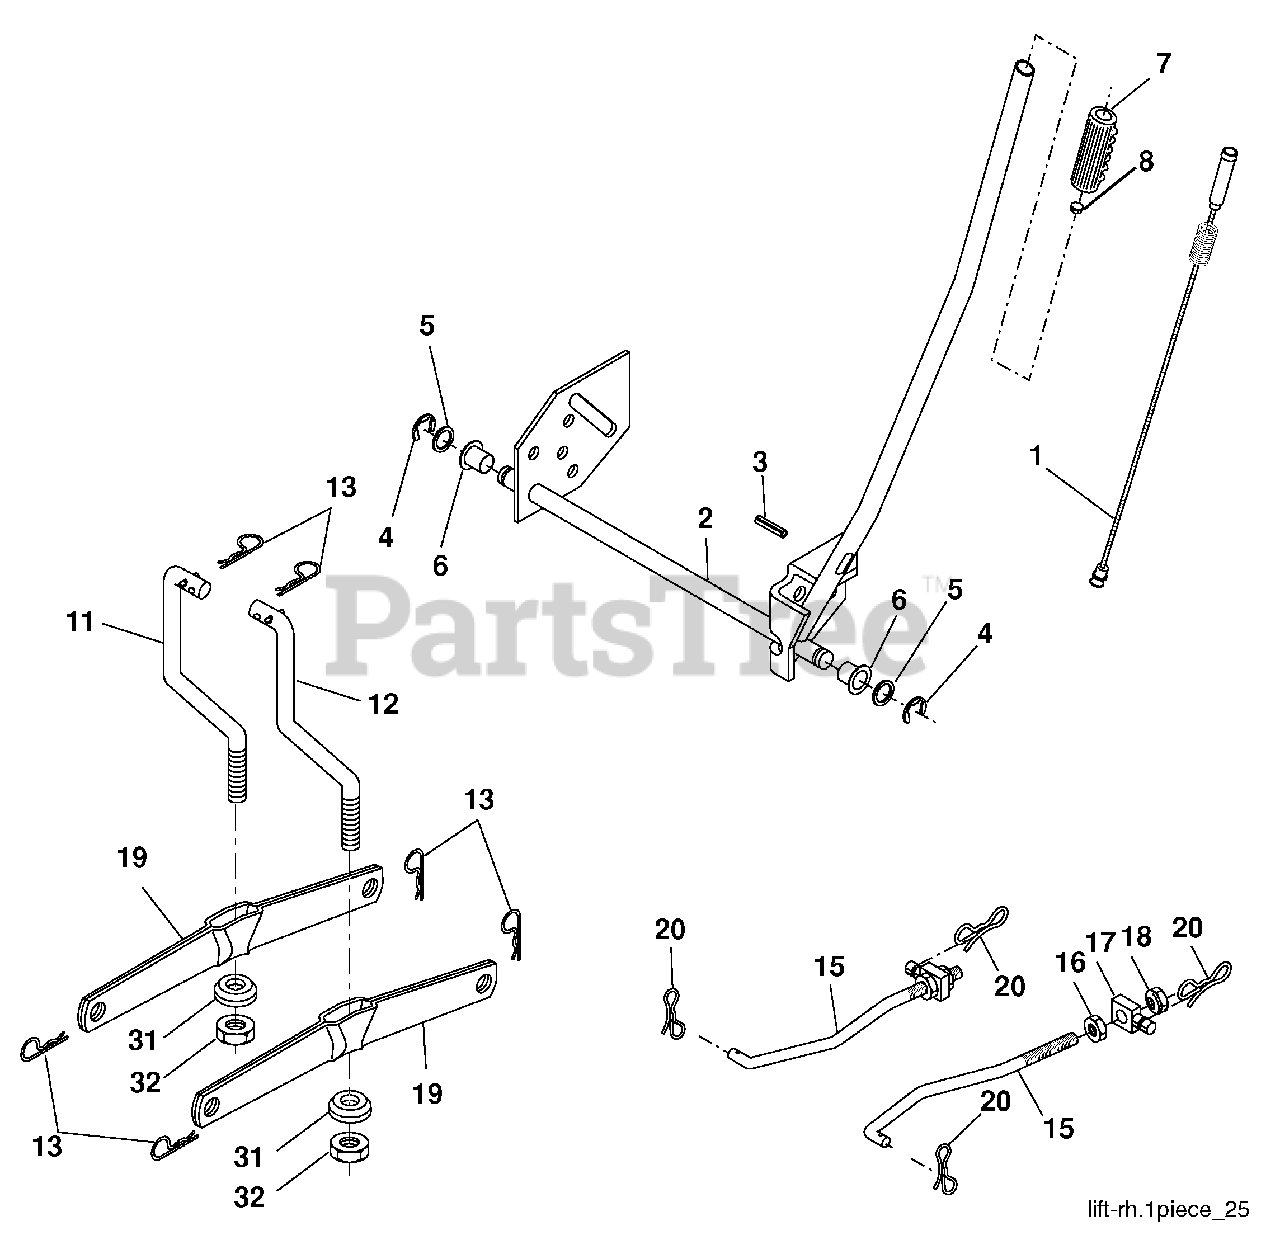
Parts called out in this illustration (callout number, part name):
1	Wire Asm Inner/Sprg w/plunger
2	Shaft Asm Lift RH
3	Pin Groove 1 500 Zinc
4	E Ring #5133-62
5	Washer 21/32 x 1 x 21 Ga.
6	Bearing Nylon Blk 629 Id
7	Grip Handle Bicycle Matte Blk
8	Button Plunger Black
11	Link Lift LH Fixed Length
12	Link Lift RH Fixed Length
13	Retainer Spring
15	Link Front
16	Nut Jam Hex 1/2-13 unc
17	Trunnion
18	Nut Lockw/Wsh 1/2-13 unc
19	Arm Suspension Rear
20	Pin Cotter 7/16 Bow Tie Lock
31	Bearing Pvt Lift
32	Nut Crownlock 3/8-24
